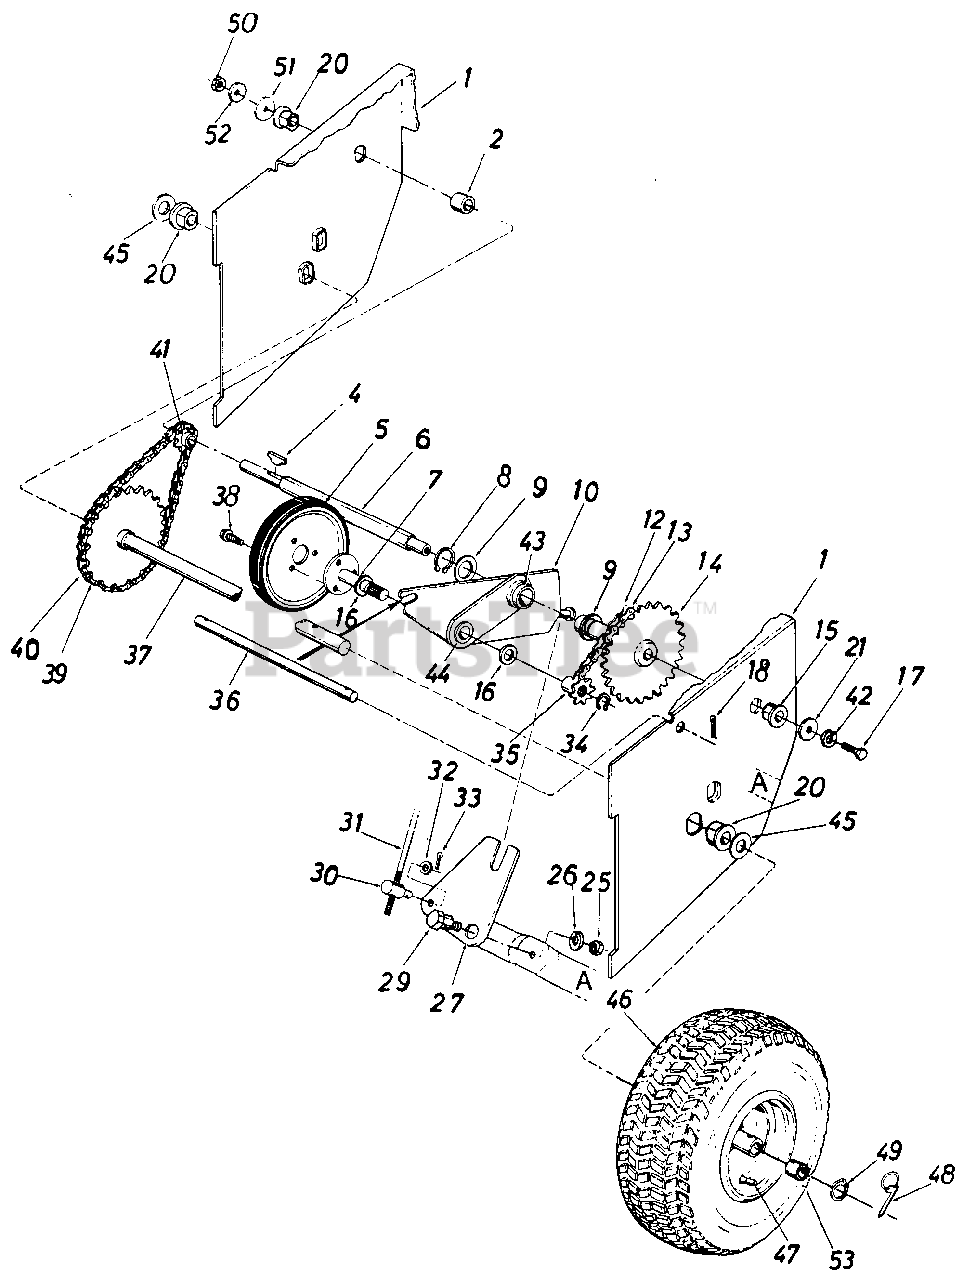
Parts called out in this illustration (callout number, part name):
1	FRAME ASSY
4	KEY-HI-PRO #4-3/32X5/8 DIA-HDN
5	WHEEL ASSY-FRICTION
7	PLATE ASSY-FRICTION WHEEL MTG
8	RING-SNAP FOR 1.00 DIA SHAFT
9	WASHER-FL-1.03 ID X 1.62 X .03 HD
10	BRACKET ASSY-SLIDING
12	CHAIN X 35 LINKS
13	#41 MASTER LINK 1/2 PITCH TYPEII
14	SPROCKET ASSY-32T
15	BEARING-FLANGE
16	WASHER-FL
17	SCREW-HEX 5/16-18 X .62
18	PIN-COTTER-3/32 DIA X .75
20	BEARING-FLANGE W/FLATS
21	WASHER-FL-.312 X 1.125 X .125
25	NUT-HEX JAM 3/8-18
26	WASHER-LOCK-3/8
27	BRACKET-LINKAGE
29	SCREW-SHLD .625 DIA X .163
30	FERRULE
31	ROD-SHIFT
32	WASHER-FL-.344 X .62
33	PIN-COTTER-3/32 DIA X .75
34	RING-C SNAP
35	SPROCKET-7T
37	AXLE ASSY-WHEEL
38	SCREW-HEX WASH SF TAPP
39	#41 CHAIN 1/2" PITCH X 43 LINK
40	#41 MASTER LINK 1/2 PITCH TYPEII
41	SPROCKET-CENTER #41-8T
42	WASHER-LOCK-5/16
43	BEARING
44	BEARING-FLANGE .630 ID
45	WASHER-FL-.760ID X 1.49OD X .06HDN
46	WHEEL ASSY-SNOW HOG-13X5
48	PIN-CLICK-5/16 DIA X 1.75LG
49	RING-SNAP FOR .750 DIA SHAFT
50	NUT-HEX INS L-1/2-20
51	WASHER-FL-.546 X 1.28 X .090
52	WASHER-BELL .505 ID X 1.00 OD
53	BEARING-SLEEVE
